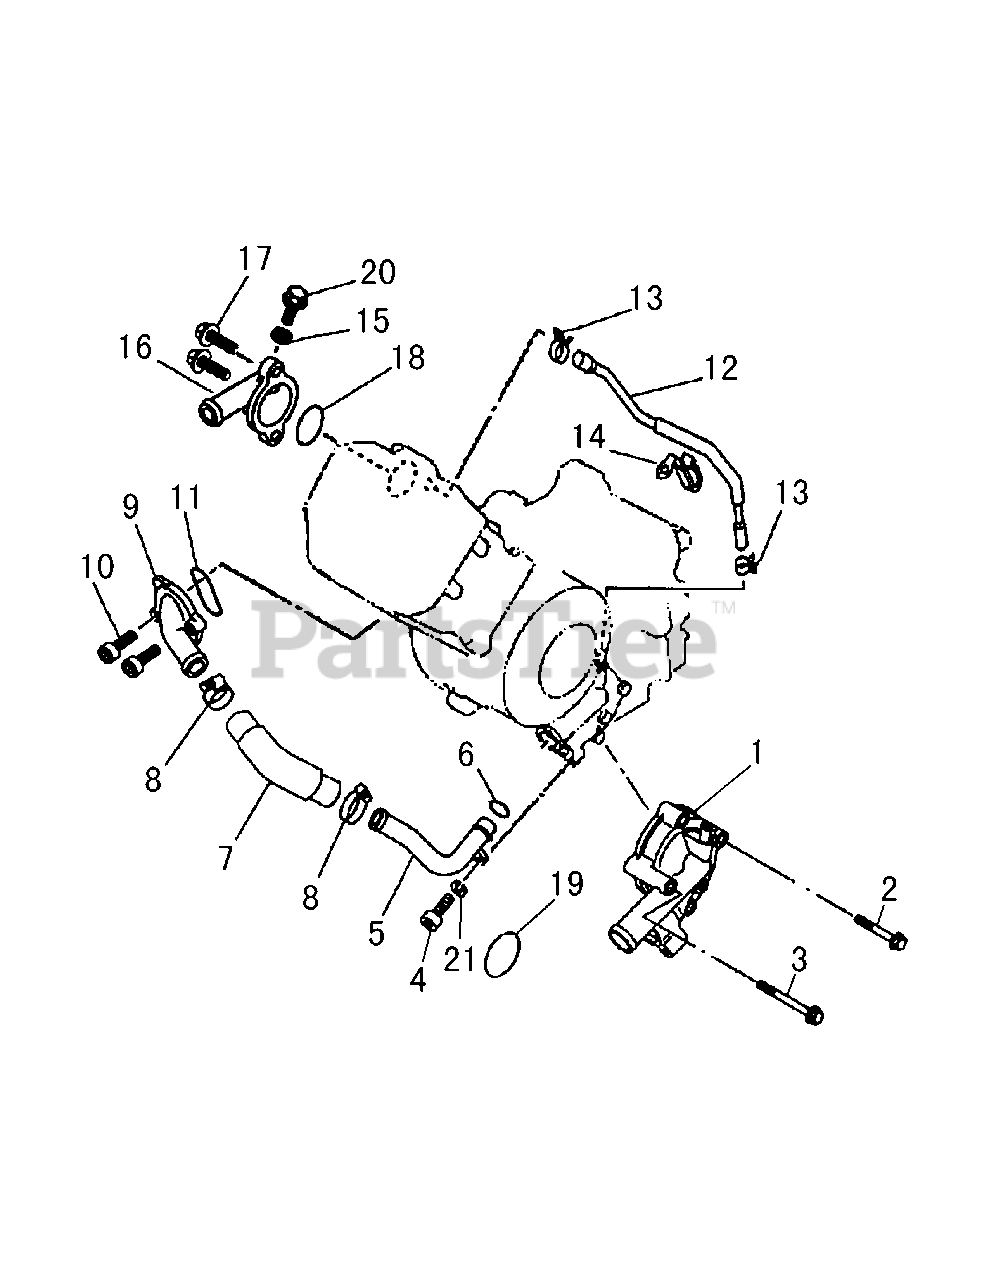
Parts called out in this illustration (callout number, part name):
1	Water Pump-Comp
2	Flangebolt M6X45
3	Flangebolt M6X65
4	Flangebolt M6X16
5	Water Pipe II
6	O-Ring 20.7X2.6
7	Water Pipe III
8	Water Pipr Clip
9	Cylinder Inlet-Wat
10	Flangebolt M6X20
11	O-Ring 33.4X2.4
12	Water Pipe I
15	Aluminum Washer 6×12×1.5
16	Cover-Thermostat
17	Flangebolt M6X20
18	Thermostat Cover O-ring
19	O-Ring 34.2X2.5
20	Flangebolt M6X12
